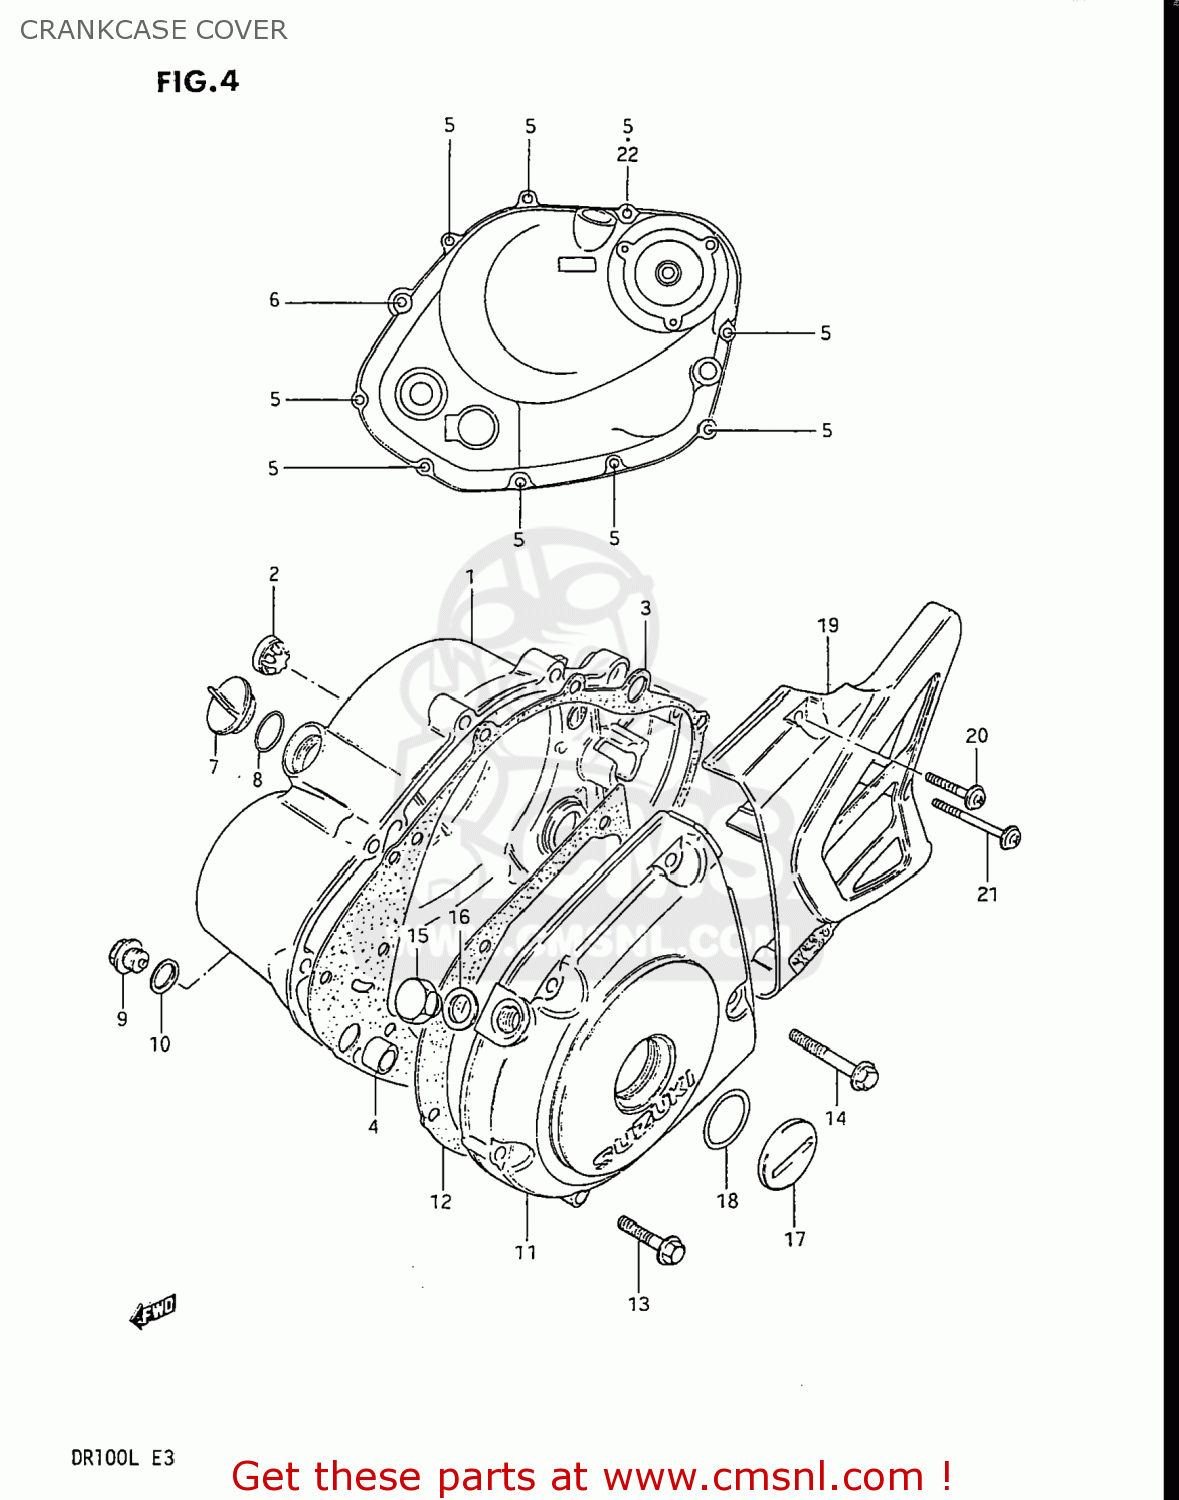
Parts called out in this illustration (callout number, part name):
1	COVER,CLUTCH
2	LENS,OIL LEVEL CHECK
3	GASKET,CLUTCH COVER (MCA)
4	PIN
5	BOLT 6X30
6	BOLT
7	PLUG
8	O RING(D:3.1,ID:16.8)
9	PLUG(14X12)
10	GASKET(14X19.2X2) (NAS)
11	COVER,MAGNETO
12	GASKET,MAGNETO COVER (MCA)
13	BOLT 6X30
14	BOLT 6X40
15	PLUG(12X9)
16	GASKET(12.1X16.2X3.7) (NAS)
17	PLUG
18	O RING(D:3.1,ID:22.7)
19	COVER,SPROCKET
20	SCREW
21	SCREW
22	GASKET(5.8X13X1.2) (NAS)
